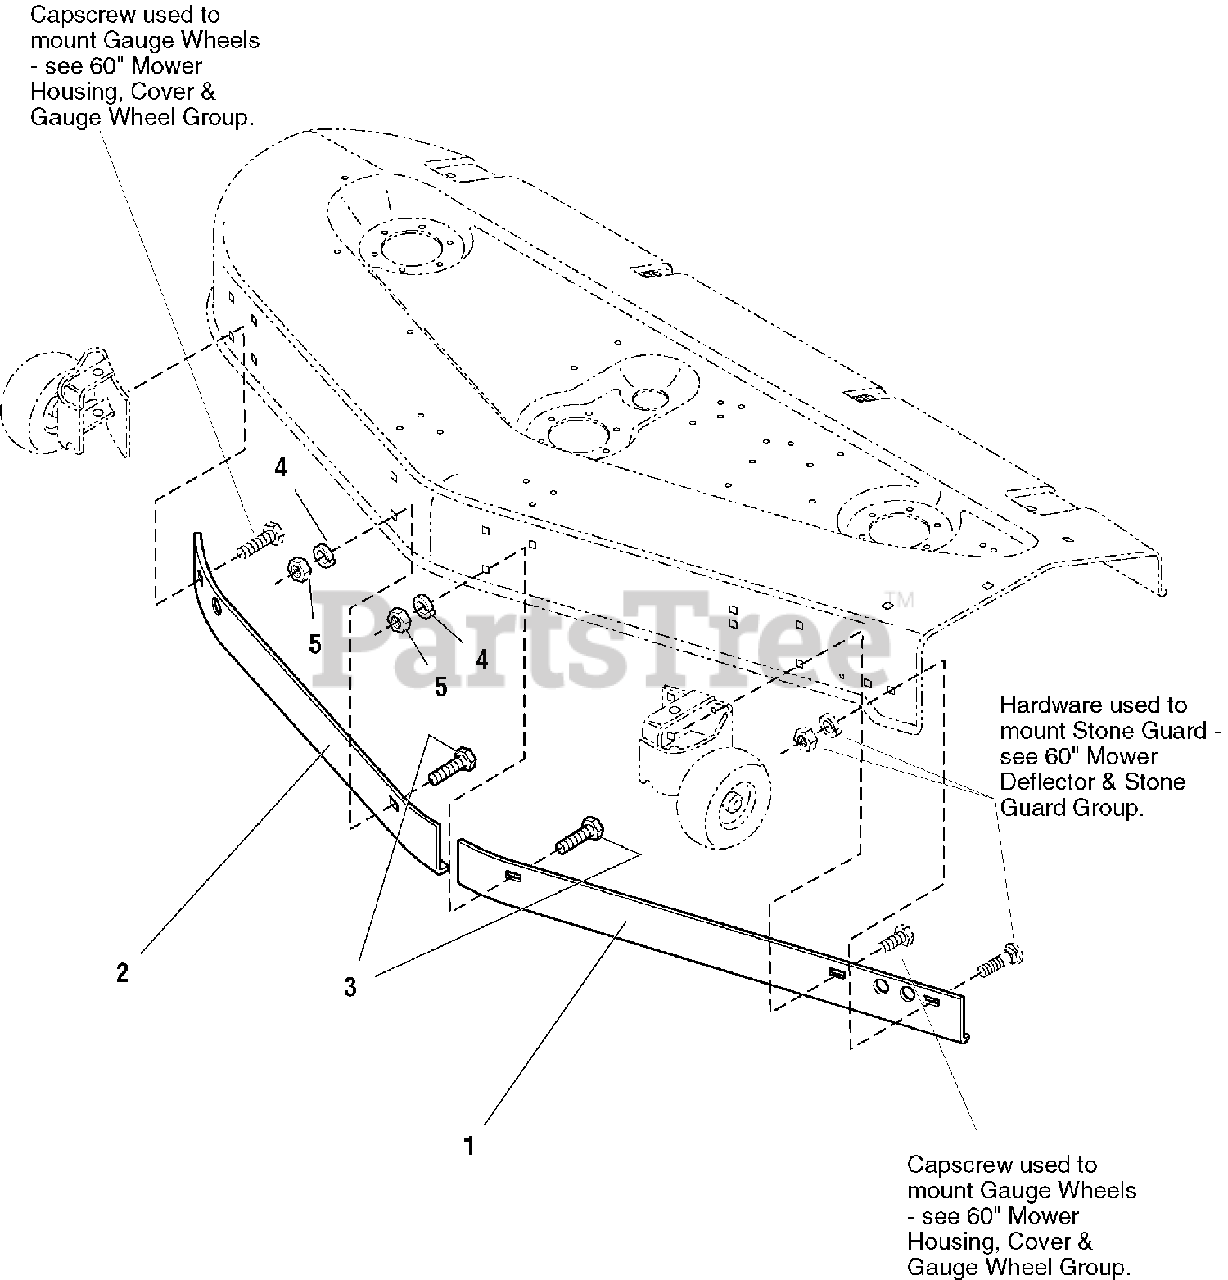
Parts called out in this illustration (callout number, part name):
1	BAFFLE, L.H.
2	BAFFLE, R.H.
3	CAPSCREW, Hex Head, 3/8-16 x 1
4	LOCKWASHER, 3/8
5	NUT, 3/8-16
